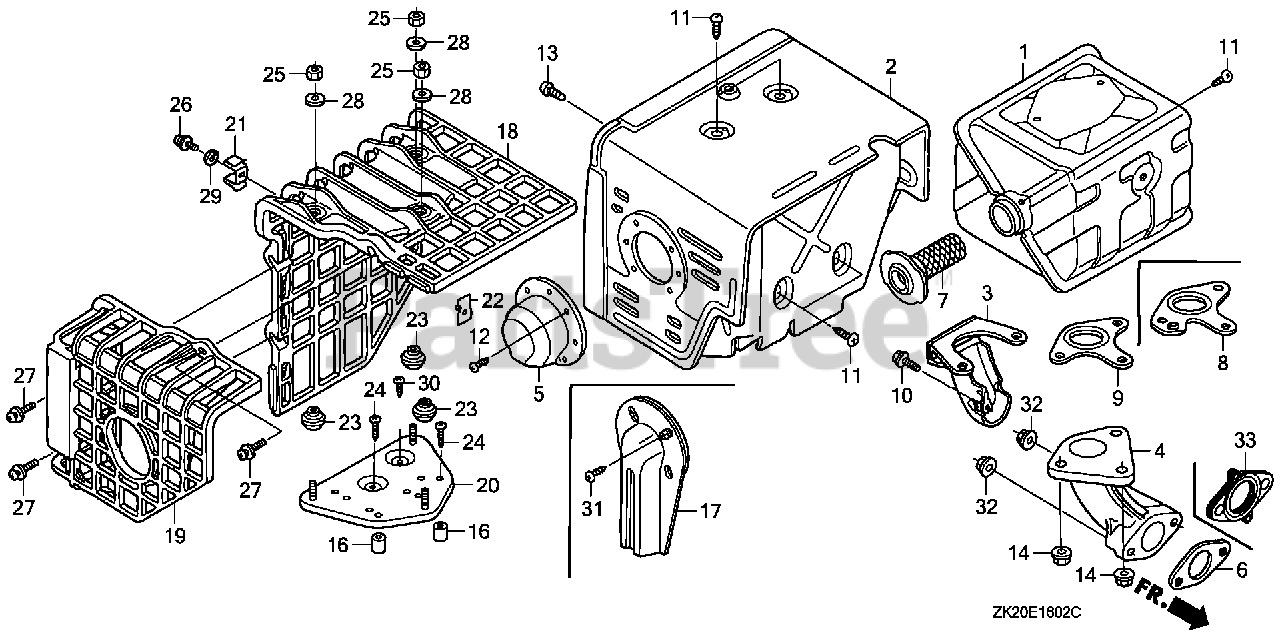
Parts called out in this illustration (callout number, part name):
1	MUFFLER (100DB)
2	PROTECTOR, MUFFLER
9	GASKET, MUFFLER (NIPPON LEAKLESS)
11	SCREW, TAPPING (5X8)
13	SCREW, TAPPING (6X10)
14	NUT, FLANGE (8MM)
32	NUT, FLANGE (8MM)
33	GASKET, EX. PIPE
